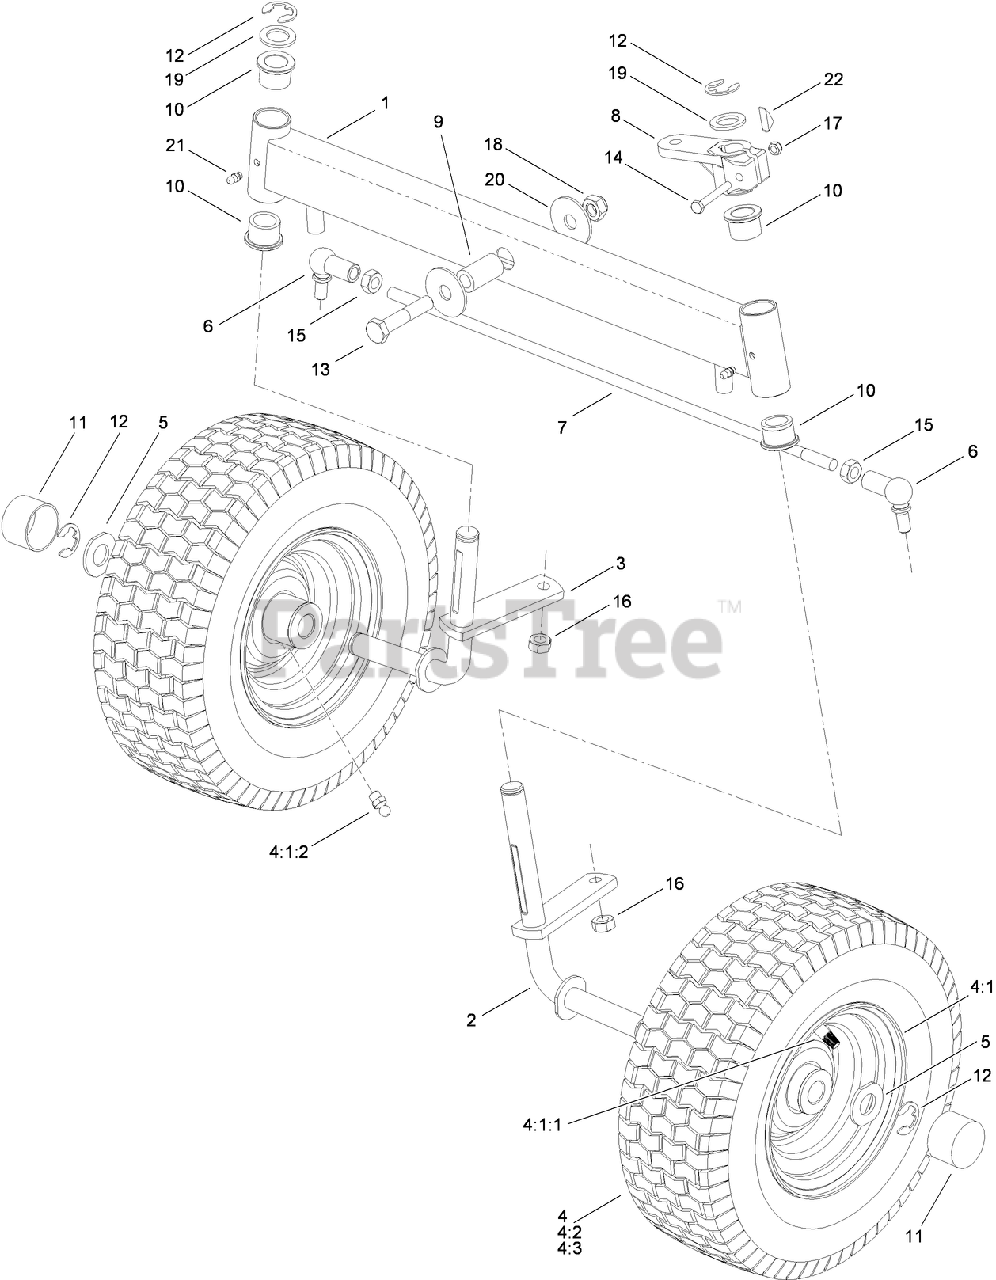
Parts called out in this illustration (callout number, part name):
1	FRONT AXLE ASM
2	SPINDLE-LH
3	SPINDLE-RH
4	Loose Parts Package
4:1	FRONT RIM ASM
4:1:1	Valve-Tire
4:1:2	FITTING-GREASE
5	RETAINER-CAP, HUB
6	JOINT-BALL, ANGLE
7	TIE ROD-AXLE, FRONT
8	LEVER-SPINDLE, STEERING
9	SPACER
10	BUSHING-SWIVEL
11	CAP-HUB
12	CLIP-SPRING
13	SCREW-HH
14	SCREW-HH
16	NUT-LOCK, NI
17	NUT-LOCK
18	NUT-LOCK, HEX NI
19	WASHER-FLAT
21	FITTING-GREASE
22	KEY-WOODRUFF
